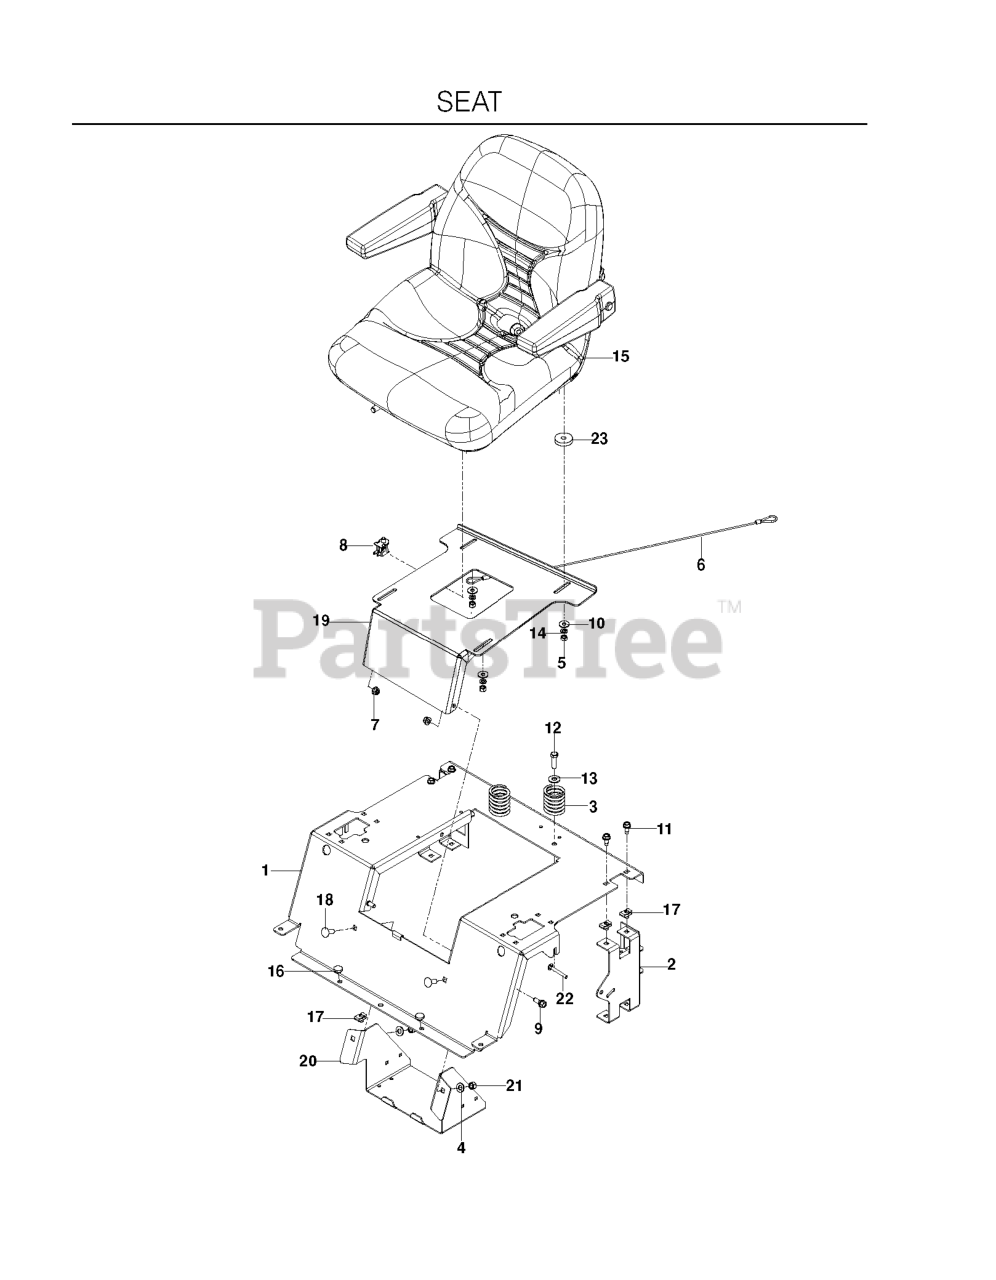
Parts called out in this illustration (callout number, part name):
1	SUPPORT, SEAT, FLAT ORANGE
2	SUPPORT, REAR SEAT, BLACK
3	SPRING, SEAT
4	WASHER 3/8 SAE FLAT
5	NUT 5/16 NYLOC
6	SEAT LANYARD
7	5/16-18 NYLOC FLANGE NUT
8	SEAT SWITCH
9	SB 5/16-18 HEX HD GD5, BLK ZN
10	WASHER 5/16 FLAT
11	BOLT 5/16-18 X 3/4
12	HCS 3/8C X 1 1/4 GR5
13	WASHER 3/8 FLAT
14	WASHER.LOCK.HVY.HLCL.SPR.5/16
15	SEAT
16	GROMMET, BUMPER
17	U-CLIP 5/16-18 NUT RETAINER
18	RHSNB 3/8C X 1
19	PAN, SEAT, ORG
20	BOX, BATTERY, BLACK
21	NUT 3/8-16 NYLOC
22	RHSNB 5/16-18 X 2-1/2 GR5 ZD
23	WASHER NYLON
